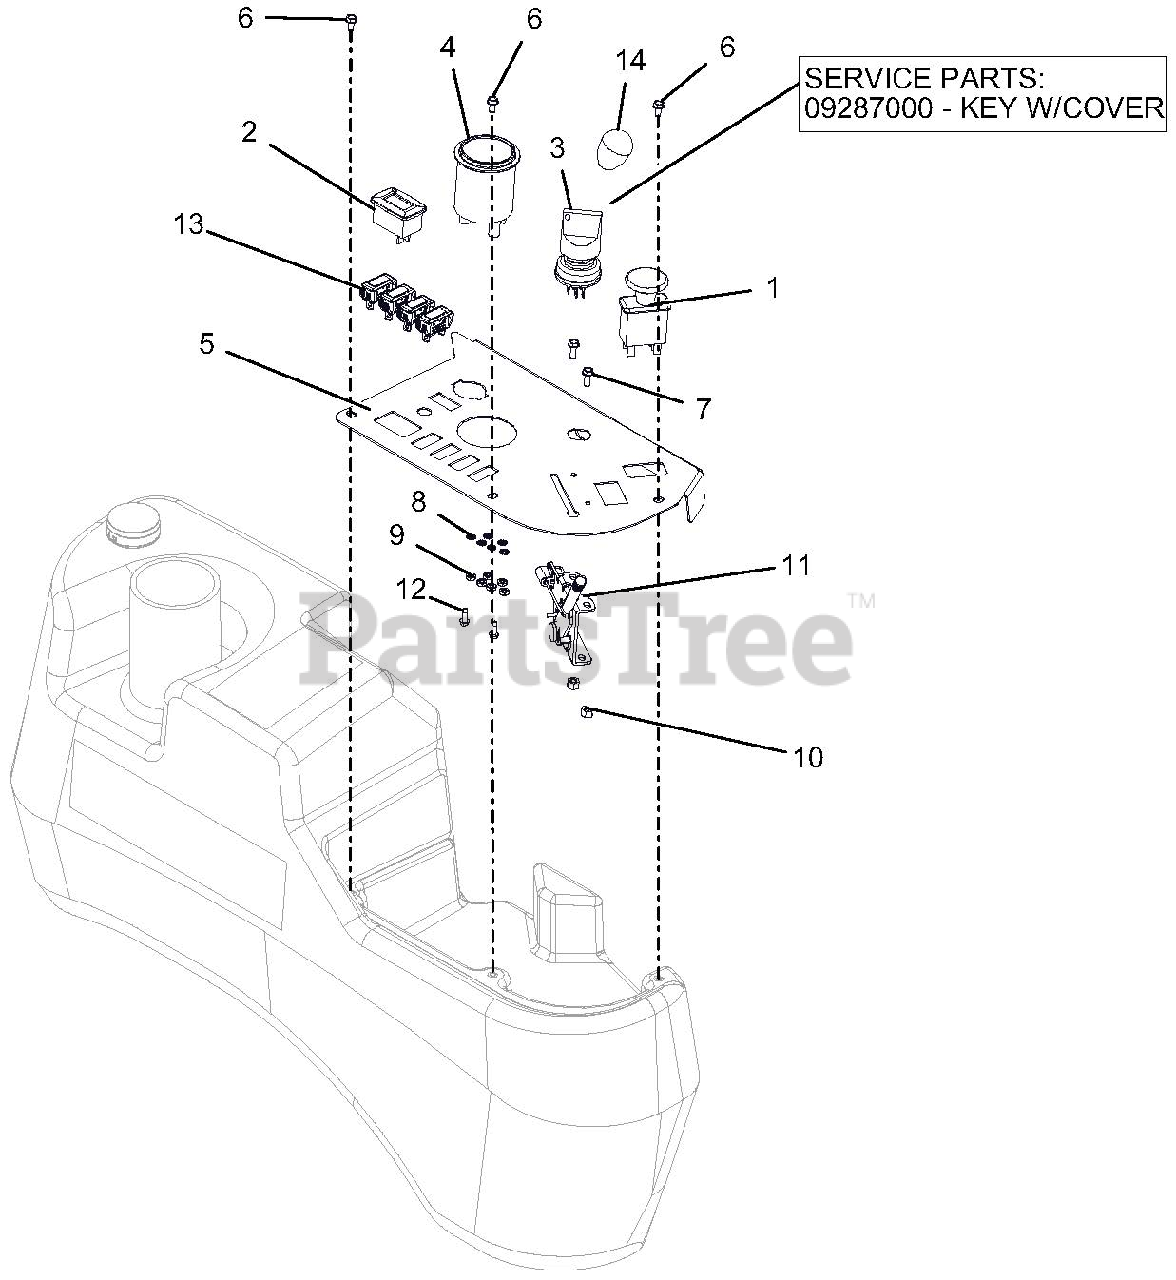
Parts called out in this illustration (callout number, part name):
1	SWITCH, CLUTCH
2	METER, HOUR W/MAINTENANCE
3	SWITCH, IGNITION
3	KEY W/COVER
4	GAGE, WATER TEMPERATURE
5	PANEL, DIESEL CONTROL
6	SCR-MCH 10-24X.38 HWHSTAINLESS
7	@SCR-MCH 10-24X.50 HWH YWZC
8	WSHR-LK-EXT #6 STAR
9	NUT-HEX 6-32 YWZC
10	NUT-LK-NYL #10-24 YWZC
11	CABLE, THROTTLE 47.37"
12	SCR-TAP 8-32X.50 HWH TR YWZC
13	LIGHT, INDICATOR
14	KNOB, CONTROL BLACK .38-16X.50
